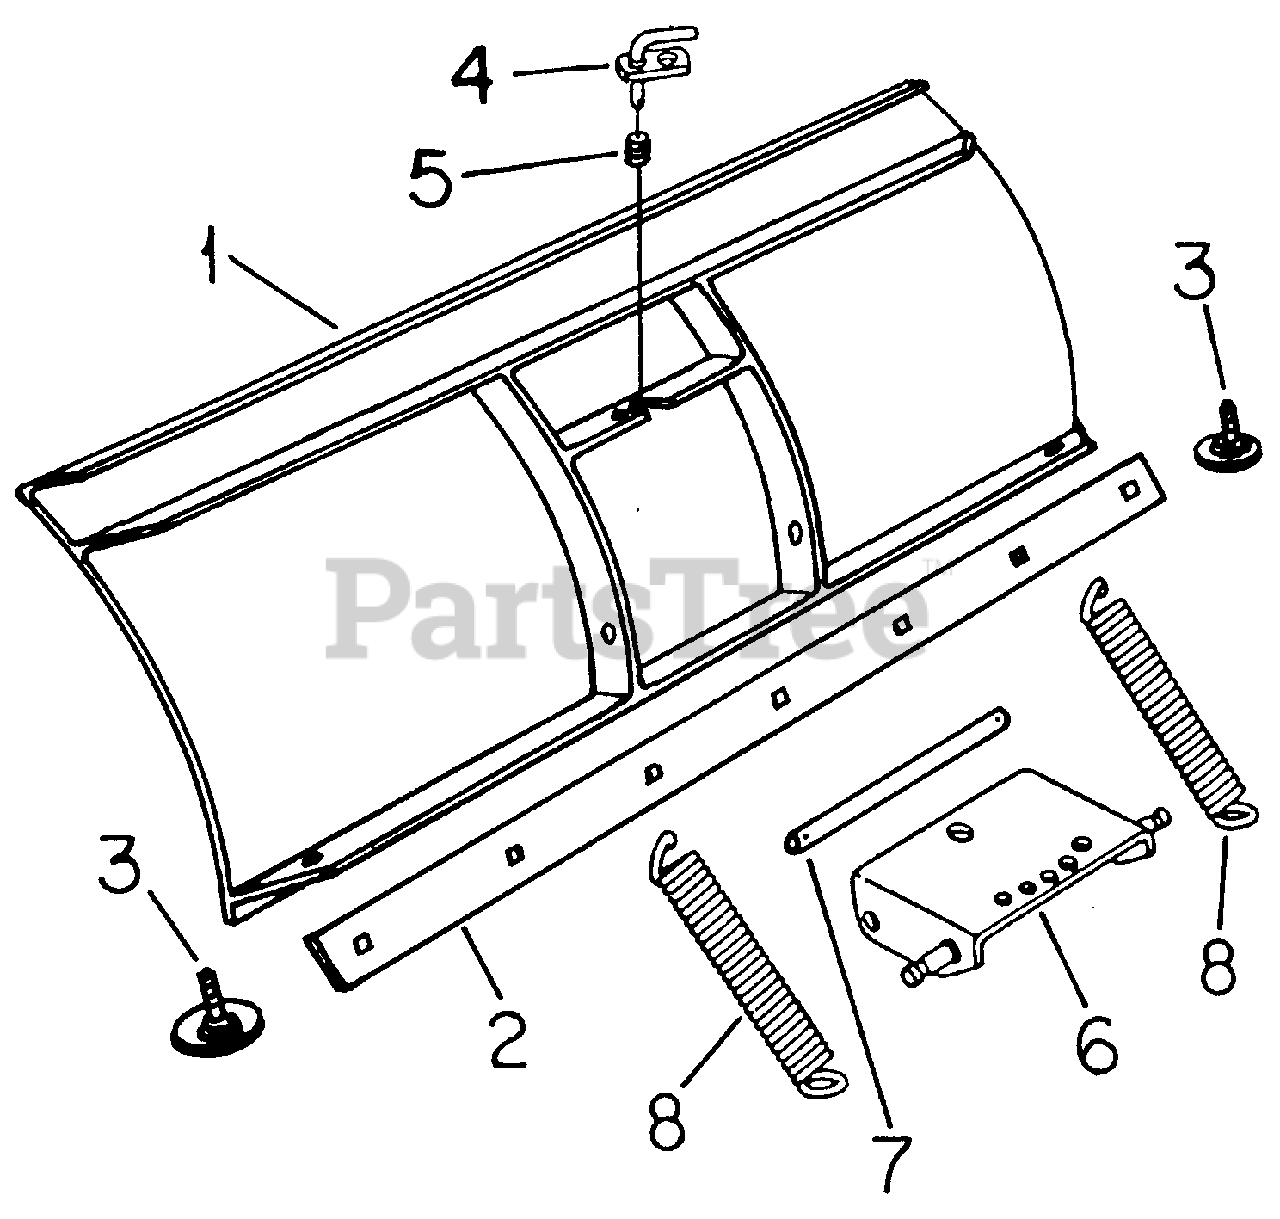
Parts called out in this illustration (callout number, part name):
3	SHOE ASSY, SKID
4	LOCK ASSY, SPRING TRIP
5	SPRING, COMPRESSION
6	FRAME ASSY, PIVOT
7	ROD, BLADE PIVOT PIN, 5/32 X 1-1/4 COT
8	SPRING, EXTENSION
